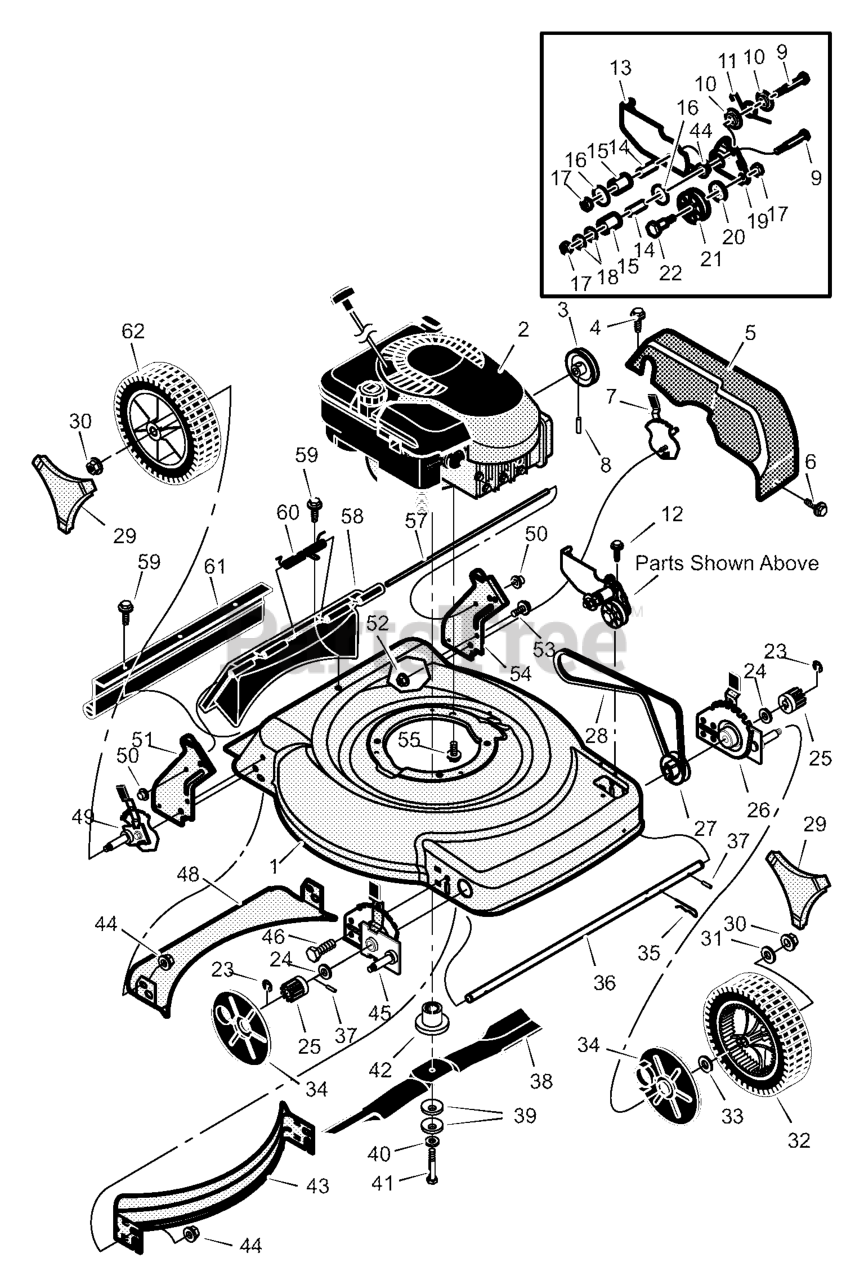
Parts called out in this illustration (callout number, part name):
1	Housing
2	Engine *
3	Pulley, Drive
5	Cover, Belt (Gray)
7	Adjuster, Left Rear Height
8	Pin, Spring
10	Spacer, Idler Arm
12	Screw
13	Bracket, Idler Support
14	Bearing, Idler
15	Pulley, Idler
17	Nut
18	Washer
19	Arm, Pivot
20	Spacer, Idler
21	Pulley, Idler
22	Bolt, Shoulder
25	Gear, Pinion
26	Adjuster, Left Front Height
27	Pulley, Axle
29	Cap, Hub
30	Nut, Flange
31	Washer
32	Wheel & Tire, Front
34	Cover, Dust
35	Pin, Hair
37	Pin, Drive
39	Washer, Belleville
42	Adapter, Blade
43	Baffle, Front
44	Nut, Flange
45	Adjuster, Right Front Height
46	Bolt
48	Baffle, Rear
49	Adjuster, Right Rear Height
50	Push On Cap
51	Bracket, Right Handle
52	Nut, Flange
53	Bolt
54	Bracket, Left Handle
55	Bolt, Engine
57	Rod, Pivot
58	Door, Rear (Gray)
61	Guard, Rear
62	Wheel & Tire, Rear
